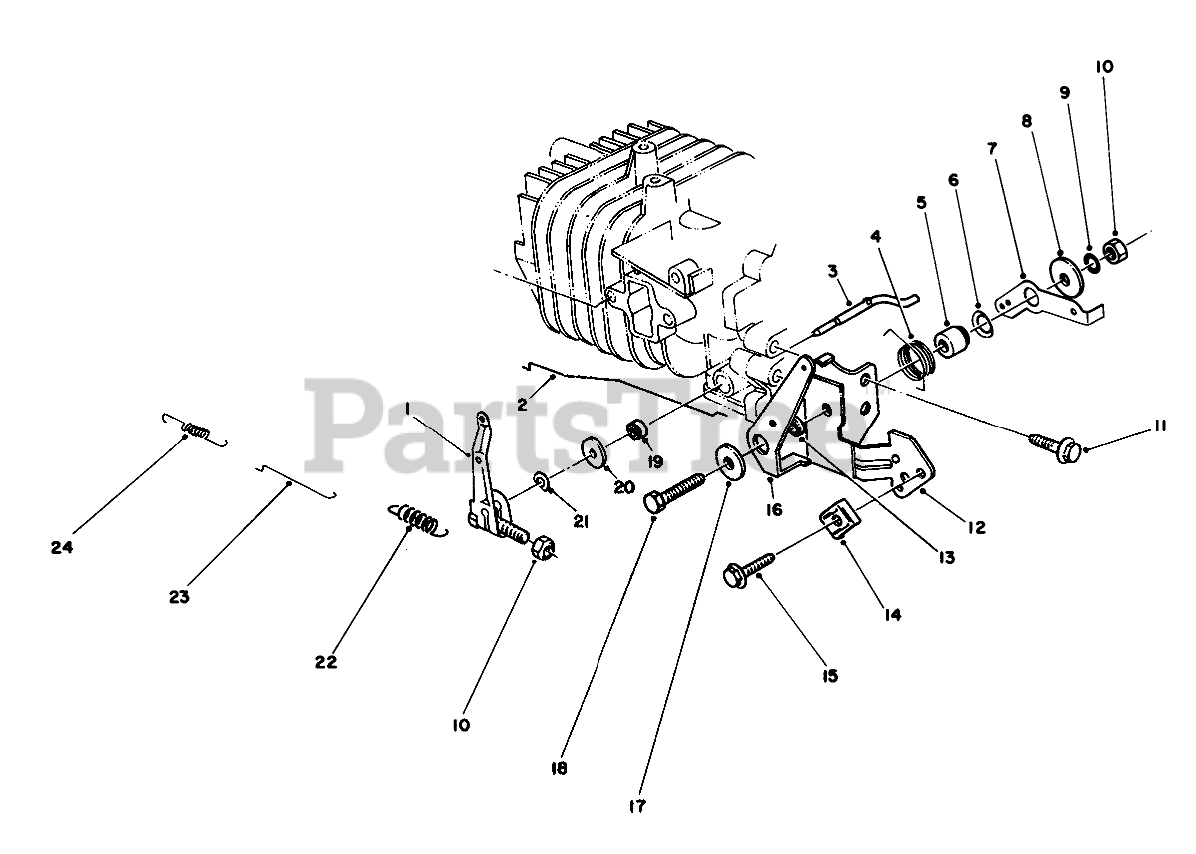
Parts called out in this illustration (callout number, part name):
1	GOVERNOR ARM
2	CHOKE ROD
3	Shaft-Govemor
4	SPRING-CHOKE LEVER
5	Gov Lever Spacer
6	Washer-Gov. Spring Lever
7	LEVER-SPRING, GOVERNOR
8	WASHER
9	LOCKWASHER
12	BRACKET-THROTTLE, CONTROL
13	SPACER-CHOKE LEVER
14	CLAMP
16	LEVER-CONTROL, CHOKE
17	WASHER
19	SEAL-OIL
20	WASHER
21	E-RING
22	SPRING-GOVERNOR
23	ROD-CARBURETOR
24	SPRING
